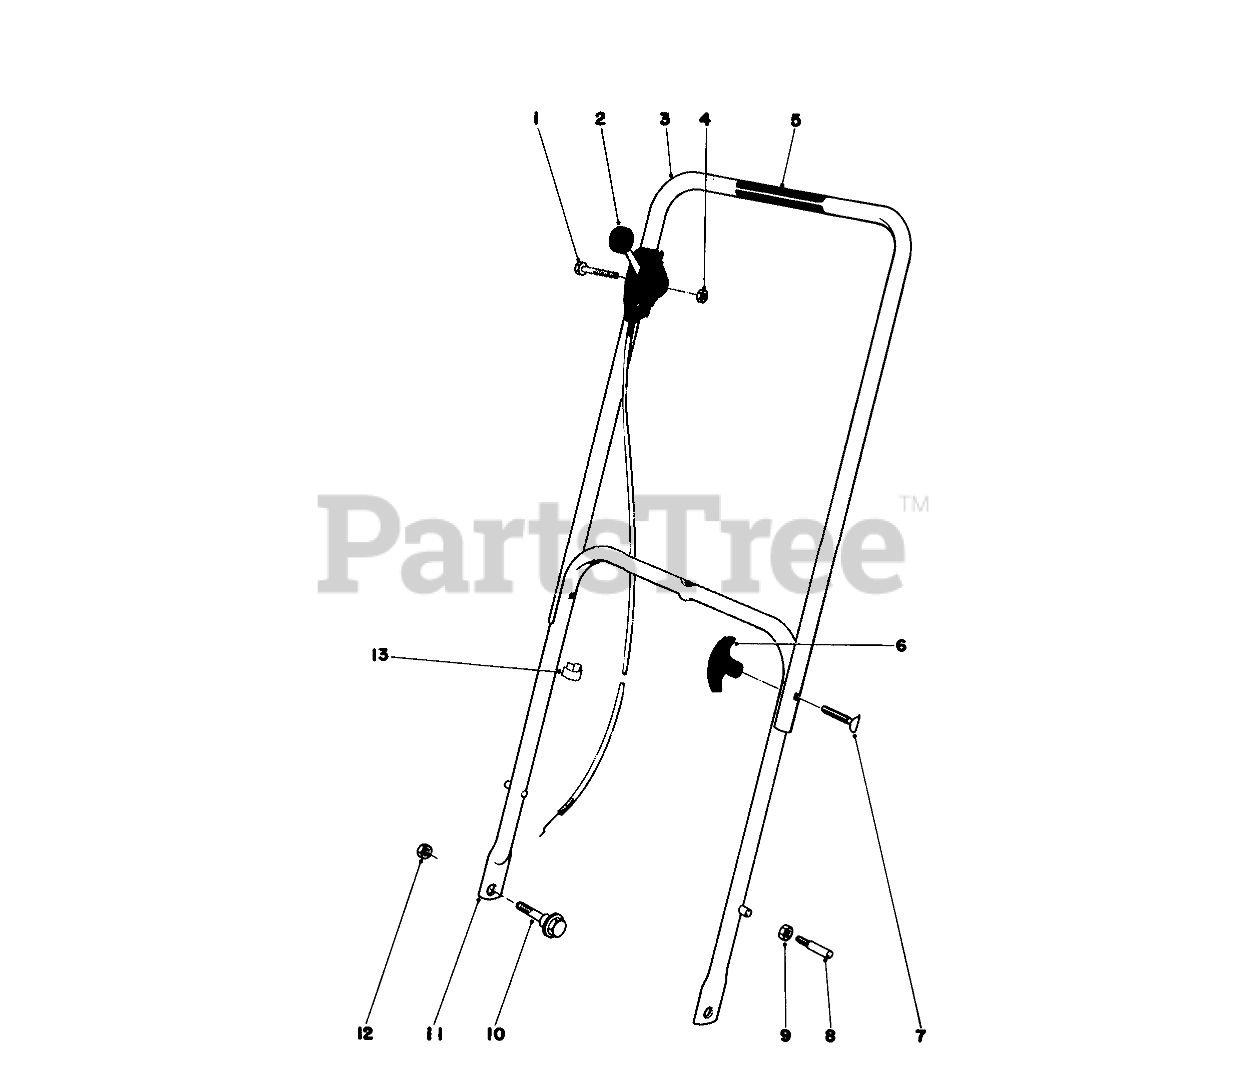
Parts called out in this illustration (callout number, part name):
1	SCREW-HH
2	Throttle Control
3	Upper Handle
4	NUT-LOCK
5	Decal
7	HANDLE SCREW
8	HANDLE PIN
9	Nut
10	SCREW-SHOULDER
11	19 LOWER HANDLE ASM
12	Nut
